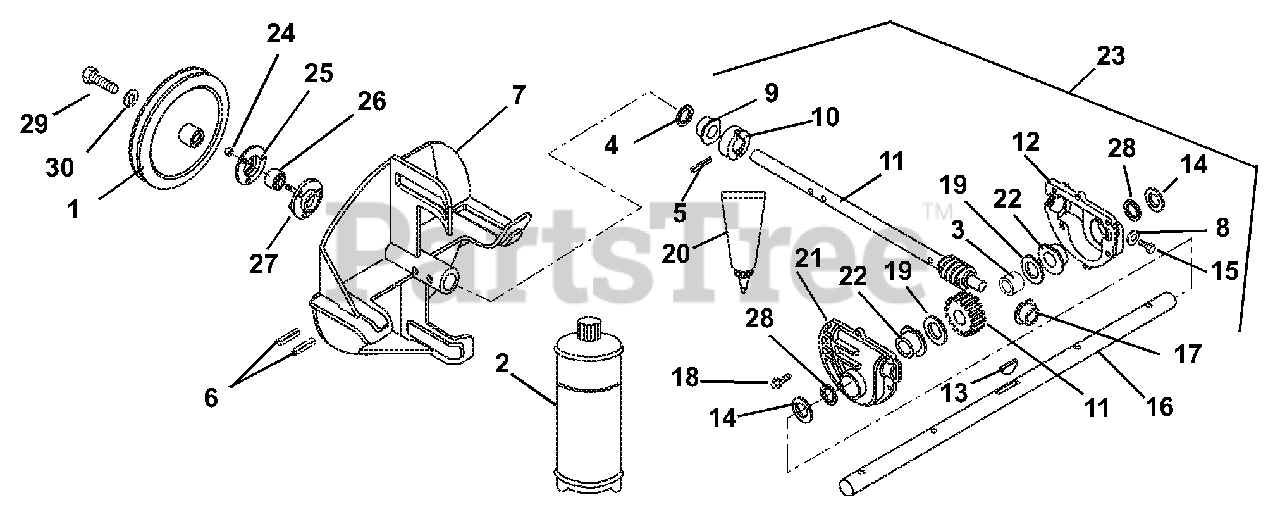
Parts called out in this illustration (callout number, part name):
1	PULLEY, 4L W/HUB, .75 X 8.5
2	ARIENS 16 OZ.BOTTLE OF L2 LUBE
3	BSHG-SLV .755X1.500X.442
4	SEAL-OIL.748X1.378X.276 RBR OD
5	@PIN-GRV .188X1.25 TP E ALLOY
6	PIN-ROLL .250X1.25
7	IMPELLER - 10"
8	WSHR-FIBER .437X.656X.032
9	BSHG-FLG .750X1.000X.750X1.250
10	THRUST COLLAR, .75" ID
11	SHAFT AND WORM GEAR ASSEMBLY
12	GEARCASE CASTING, MACHINED LH
13	KEY-WDRF .188X.625X.25 SAE 61
14	@WSHR-FL-STL.812X1.50X.135YWZC
15	SCR-TAP .38-16X.75 ROLOK YZ WX
16	SHAFT, RAKE - 24" (.750 DIA)
16	SHAFT, RAKE - 20" (.750 DIA)
17	BSHG-FLG .502X1X.750
18	@SCR-TAP .25-20X1.00 HWH TR YZ
19	WSHR-HDND-THRST .755X1.40X.062
20	LOCTITE 518 GASKET--6ML TUBE
21	GEARCASE CASTING, MACHINED RH
22	BSHG-FLG .753X1.127X.500X1.501
23	GEARCASE, 24" ALUM, SMALL CD
23	GEARCASE, 20" ALUM, SMALL CD
24	@NUT-LK-CTR .25-20 YWZC
25	BEARING FLANGE
26	BRG-BALL .750X1.750X.50
27	BEARING FLANGE
28	SEAL-OIL .750X1.375X.250
29	BLT-HEX .31-24X1.0 GR5 YZ EP80
30	WSHR-LK .312X.097 HVY YWZC
